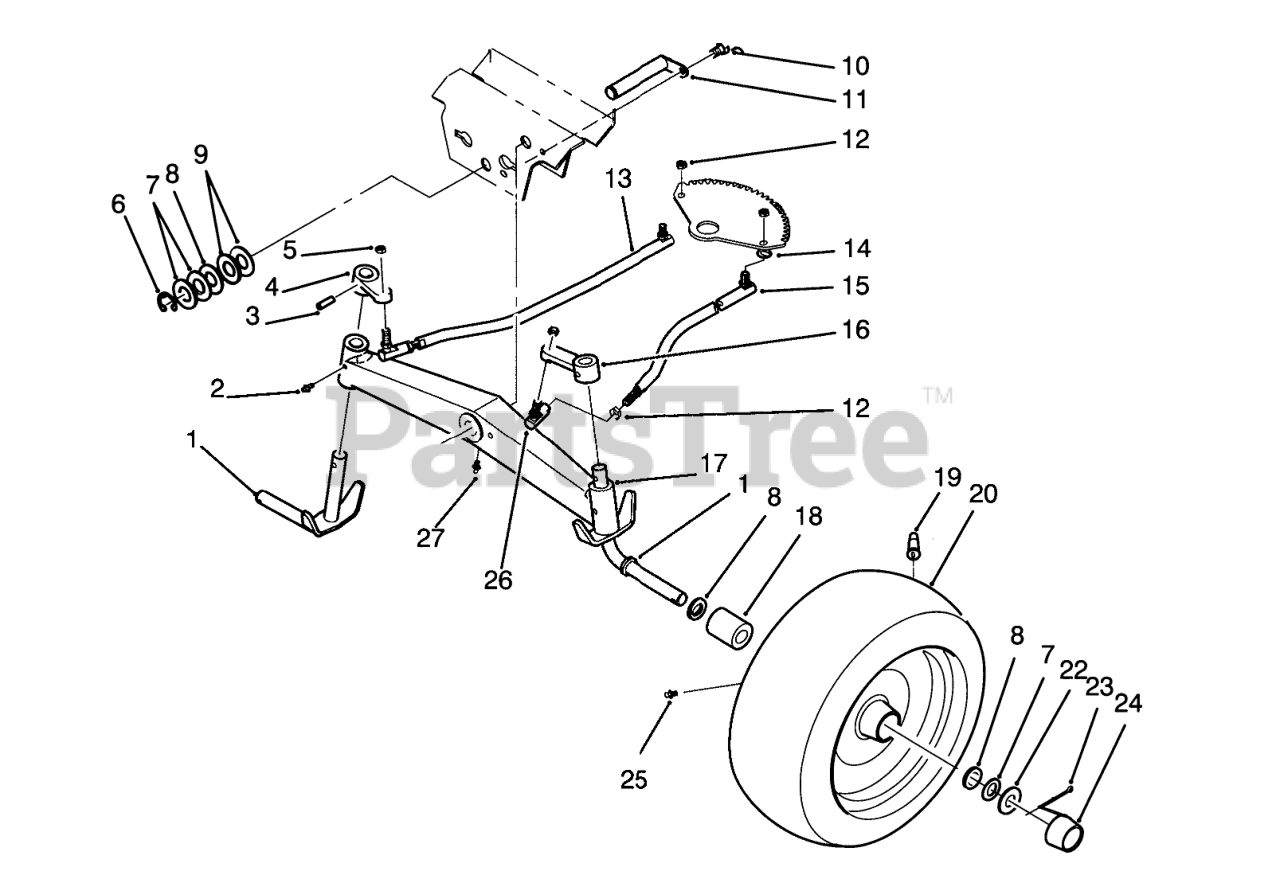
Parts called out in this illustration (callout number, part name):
1	Spindle
2	FITTING-GREASE
4	Arm-Spindle, R.H.
5	Nut
6	E-RING
7	WASHER-SHIM
8	WASHER
9	WASHER
10	Bolt
11	WLDMT-AXLE PIN R
12	NUT-6
13	Ball Joint
14	Collar
15	Steering Link Rod, L.H.
16	Arm-Spindle, L.H.
17	Axle-Front
18	BEARING-WHEEL
19	VALVE
20	Tire (16 x 6.5-8) 2-Ply -2 Wheel Axel
22	WASHER WHEEL
23	PIN-COTTER
24	HUBCAP
25	ZERK-GREASE
26	Ball Joint
27	FITTING-GREASE
